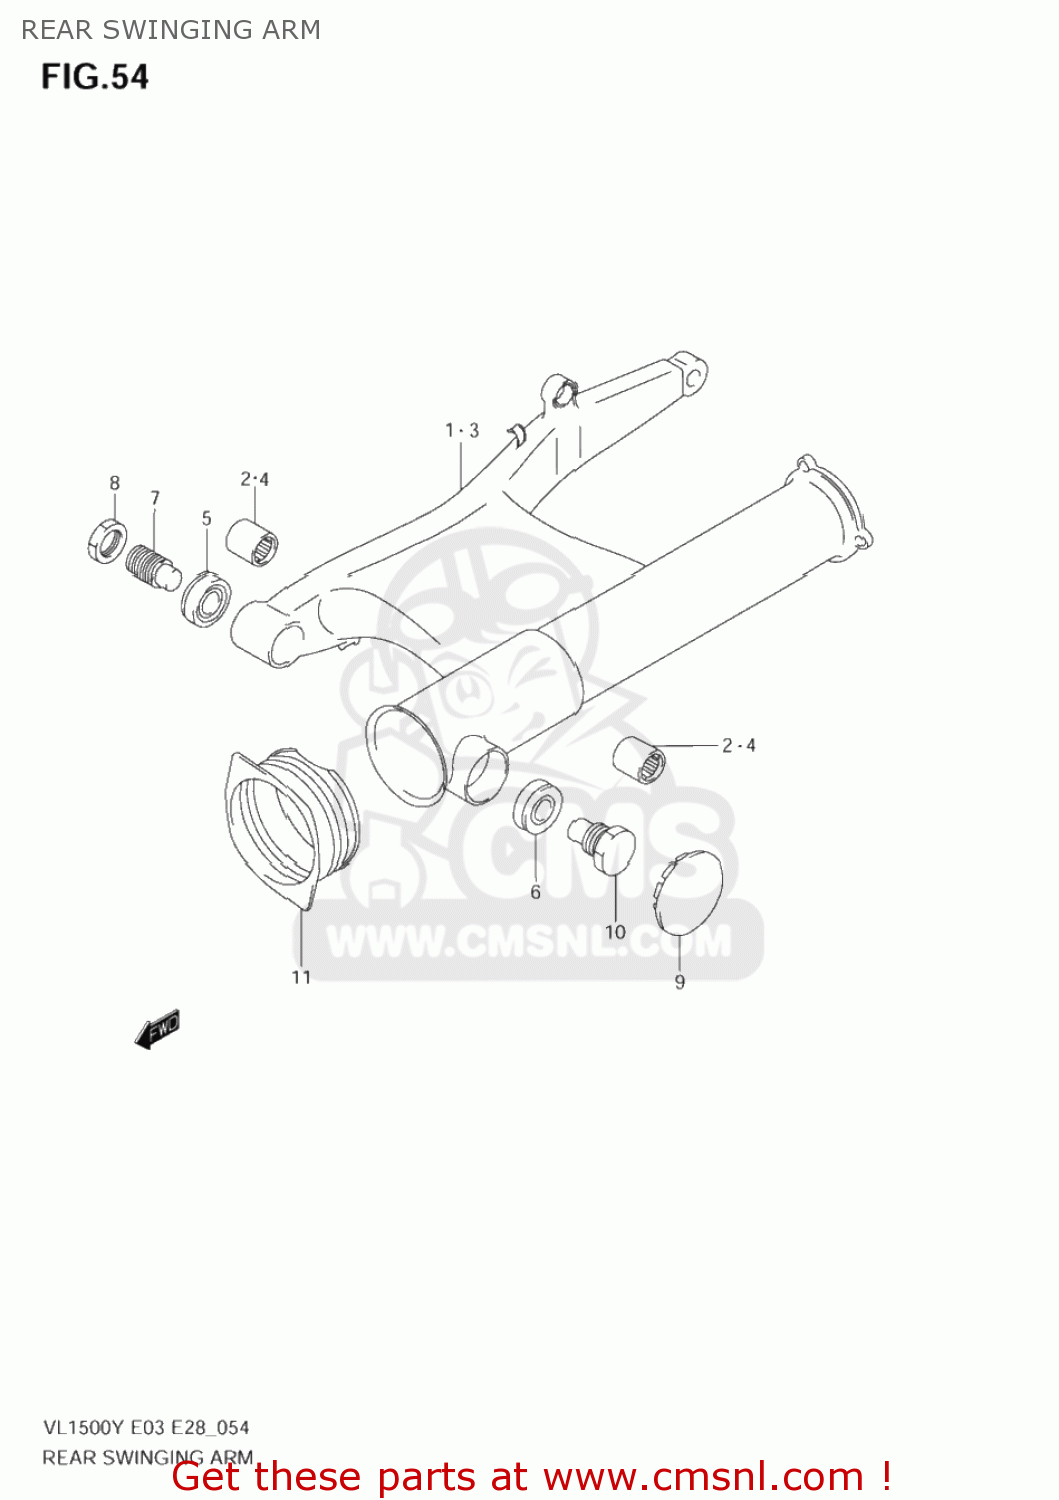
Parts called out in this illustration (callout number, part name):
1	SWING ARM COMP,REAR
2	BEARING(20X27X23.5)
3	SWING ARM SET,REAR
4	BEARING(20X27X23.5)
5	BEARING(17X40X13.25)
6	BEARING(17X40X13.25)
7	BOLT,RR SWGARM PIVOT
8	NUT
9	CAP,RR SWINGING ARM PIVOT NUT
10	BOLT,SWINGINGARM PIVOT,L
11	BOOT,PROPELLER SHAFT
